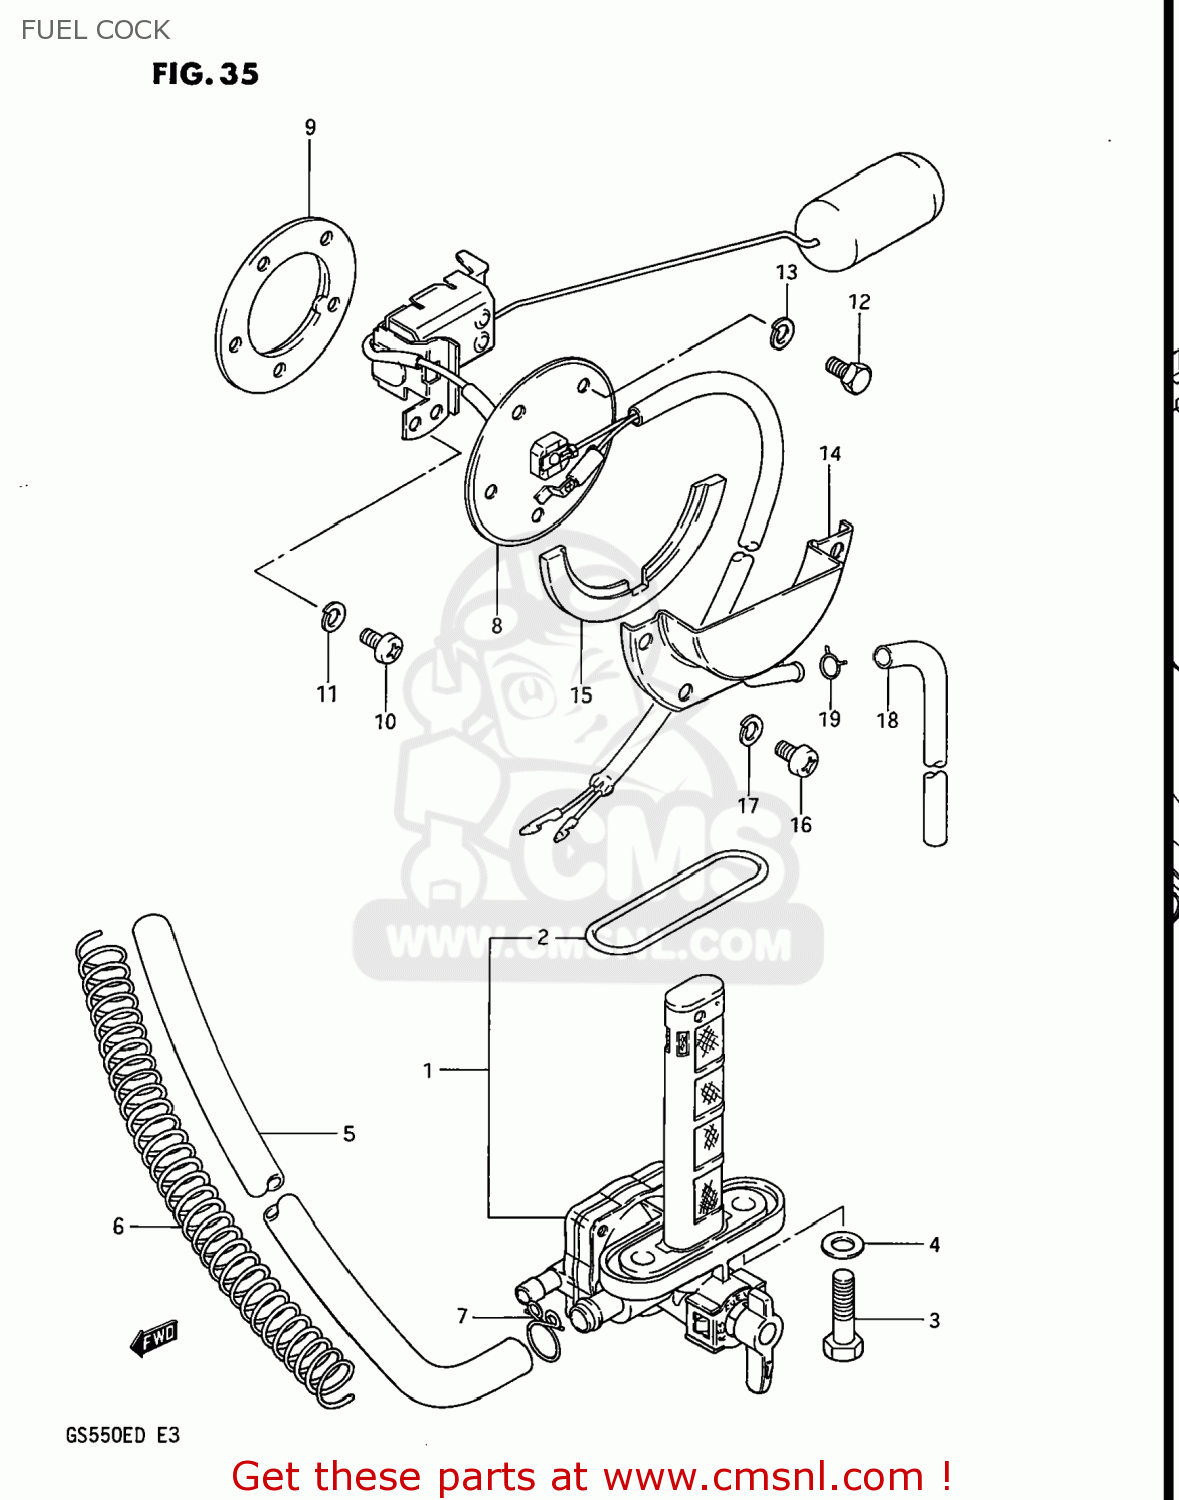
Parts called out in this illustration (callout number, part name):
1	COCK ASSEMBLY,FUEL
2	O RING
3	BOLT(6X20)
4	GASKET
5	HOSE
6	SPRING
7	CLIP
8	GAUGE ASSEMBLY,FUEL LEVEL
9	GASKET,FUEL LEVEL GAUGE (NAS)
10	SCREW
11	LOCK WASHER
12	BOLT
13	LOCK WASHER
14	PLATE,FUEL DRAIN
15	GASKET (NAS)
16	SCREW
17	LOCK WASHER
18	HOSE,FUEL
19	CLIP
